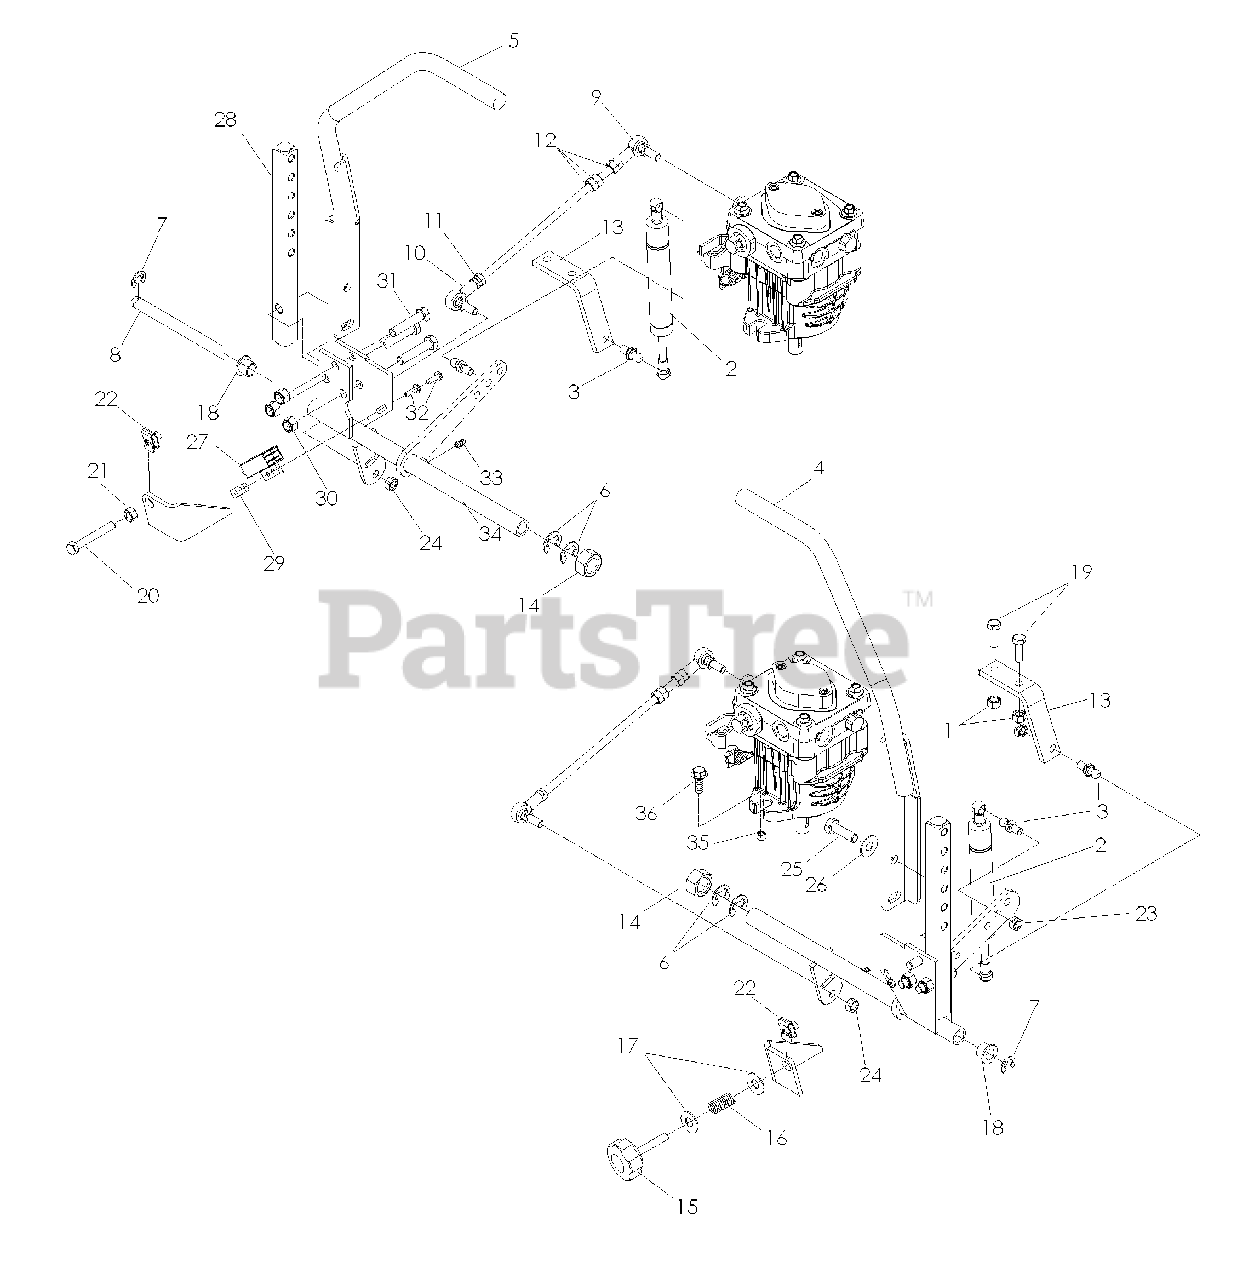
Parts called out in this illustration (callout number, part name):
1	NUT 5/16-18 HEX NYLOC
3	STUD, 10mm BALL
4	CONTROL WLDMT LT
5	CONTROL WLDMT RT
6	E-RING 5/8
7	E-RING 1/2
8	CONTROL SHAFT
9	SPHERICAL ROD END LH
10	SPHERICAL ROD END RH
11	NUT 5/16-24 HEX JAM LH
12	NUT 5/16-24 HEX
13	BRACKET DAMPENER
14	NUT 3/4-16 HEX
17	WASHER, 5/16 FLAT
19	HCS 5/16-18 x 1
20	HCS 5/16-18 x 1 3/4 TPBLT
21	NUT 5/16-18 HEX
22	RETAINER, 5/16-18 U-TYPE
23	NUT 5/16-18 HEX CTRLK
24	NUT 5/16-24 NYLOC
25	HCS 3/8-16 x 1
26	WASHER 3/8 SPRING
27	SWITCH-INTERLOCK 2P
28	ARM, CONTROL SHAFT
29	TAPPED PLATE
30	NUT 3/8-16 HEX NYLOC
31	HCS 3/8-16 x 1 3/4
32	SCREW 10-24 x .625
33	ZERK
34	CONTROL-DRIVE, LT
34	CONTROL- DRIVE, RT
35	NUT 3/8-16 HEX CTR LK
36	HCS 3/8-16 x 1 WHIZLK
